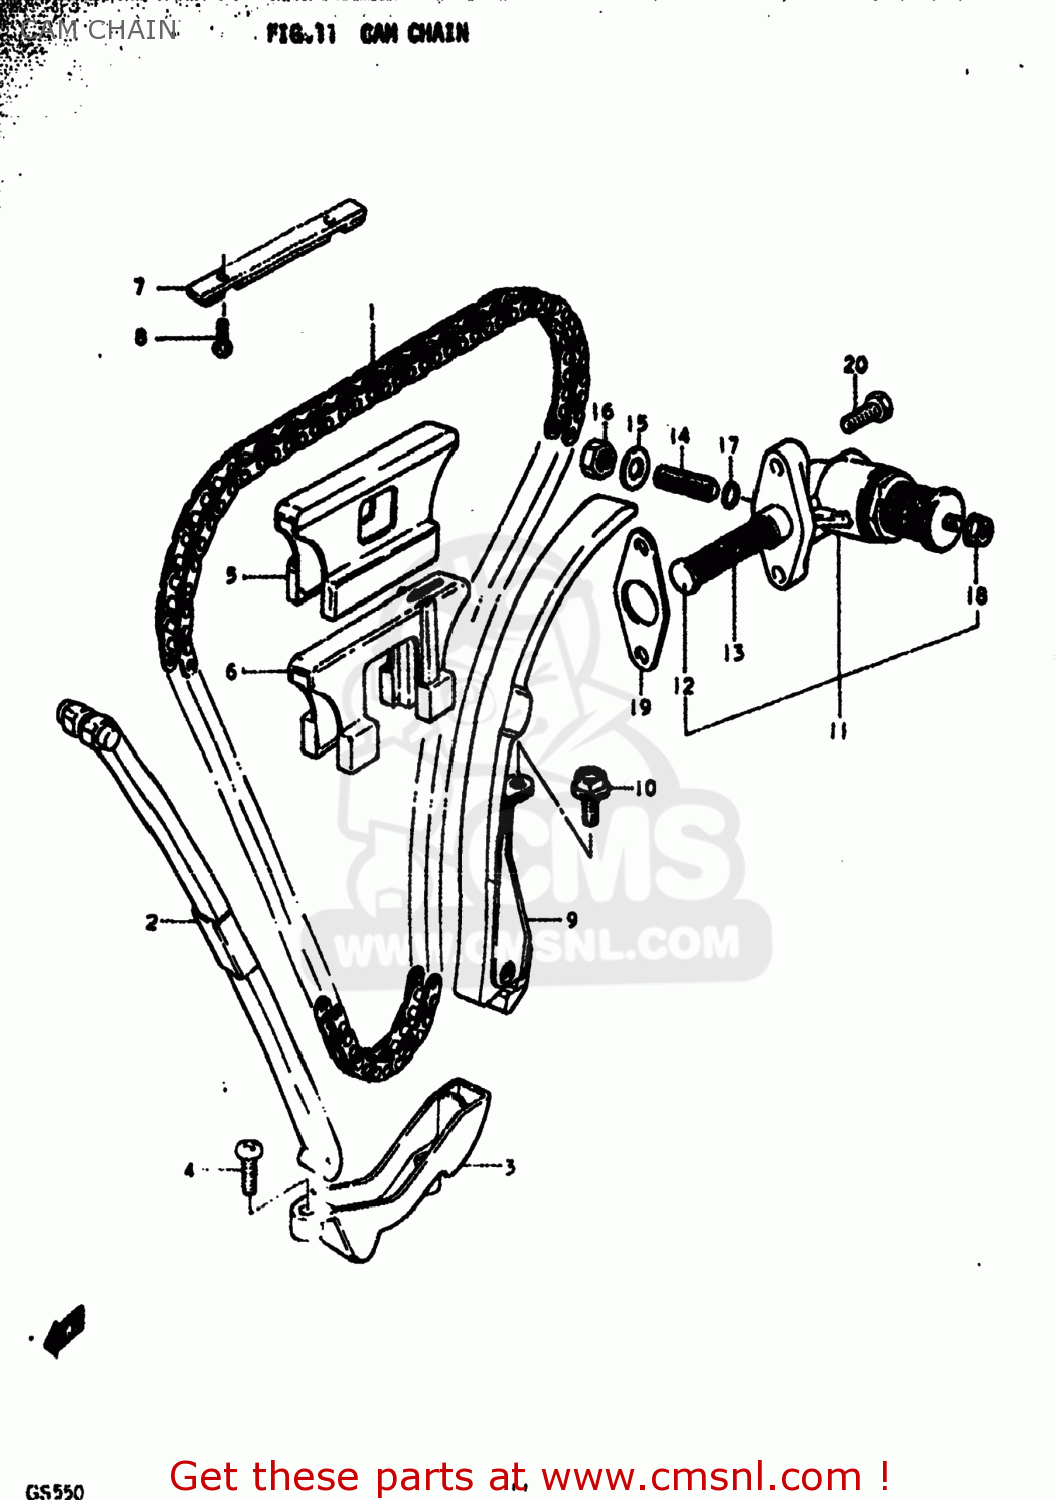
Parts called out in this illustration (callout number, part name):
1	CHAIN,CAMSHAFT DRIVE
2	GUIDE,CAM CHAIN NO.1
3	HOLDER,CAM CHAIN GUIDE
4	SCREW
5	GUIDE,CAM CHAIN
6	GUIDE,CAM CHAIN
7	GUIDE,CAM CHAIN NO.3
8	SCREW
9	TENSIONER,CAM CHAIN
10	BOLT
11	ADJUSTER ASSEMBLY,TENSIONER
12	ROD,PUSH
13	SPRING
14	SCREW
15	WASHER
16	NUT
17	O-RING
18	NUT
19	GASKET,TENSIONER ADJUSTER (MCA)
20	SCREW
